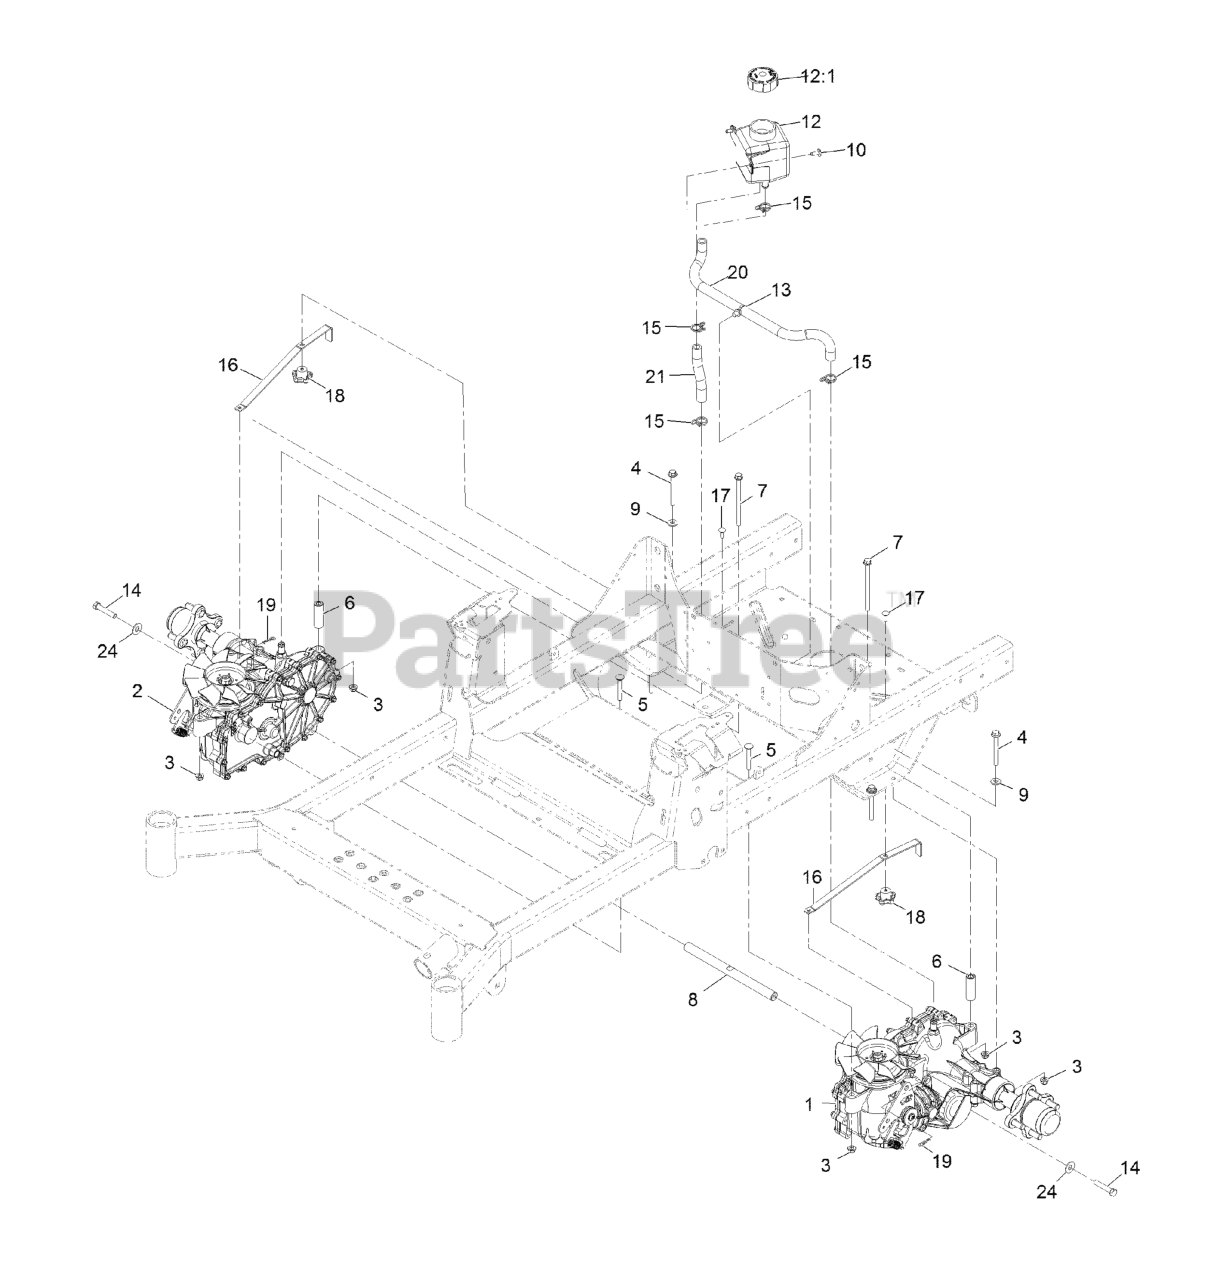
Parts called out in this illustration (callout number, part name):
1	TRANSAXLE ASM LH
2	TRANSAXLE ASM RH
3	NUT-HF, NI
4	SCREW-HHF
5	BOLT-CARR
6	SPACER-HYDRO
7	SCREW HHF
8	SHAFT-SPACER
9	WASHER-SPRING
10	SCREW-TORX
12	TANK-HYD
12:1	CAP-RESERVOIR, HYD
13	CLIP-TIE
14	SCREW-HH W/LOCTITE
15	CLAMP-HOSE
16	ARM-BYPASS, HYDRO
17	BOLT-CARR
18	KNOB-HANDLE
19	PIN-COTTER
20	HOSE-HYDRAULIC
21	HOSE-HYDRAULIC
24	WASHER-FLAT
